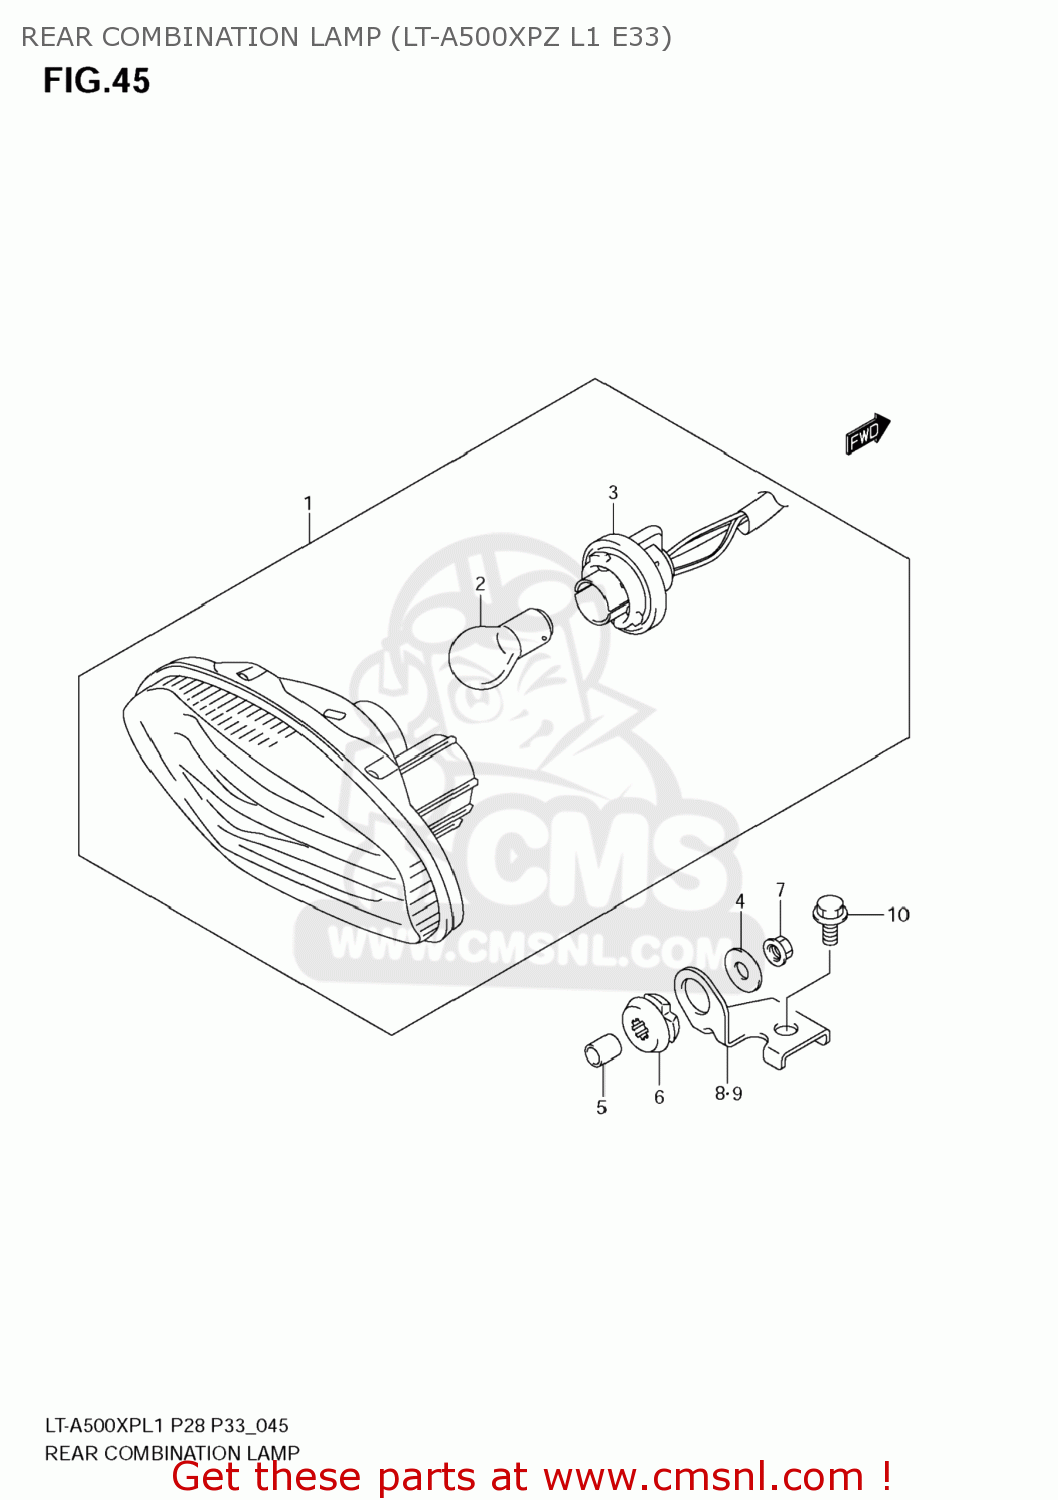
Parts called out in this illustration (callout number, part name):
1	LAMP ASSY,RR COMBINATION
2	BULB(12V21/5W,BF141-49642A)
3	SOCKET & BULB
4	WASHER(6.5X20X1.2)
5	SPACER(6.5X9X10.5)
6	CUSHION
7	NUT
8	BRACKET,RR LAMP,R
9	BRACKET,RR LAMP,L
10	BOLT
